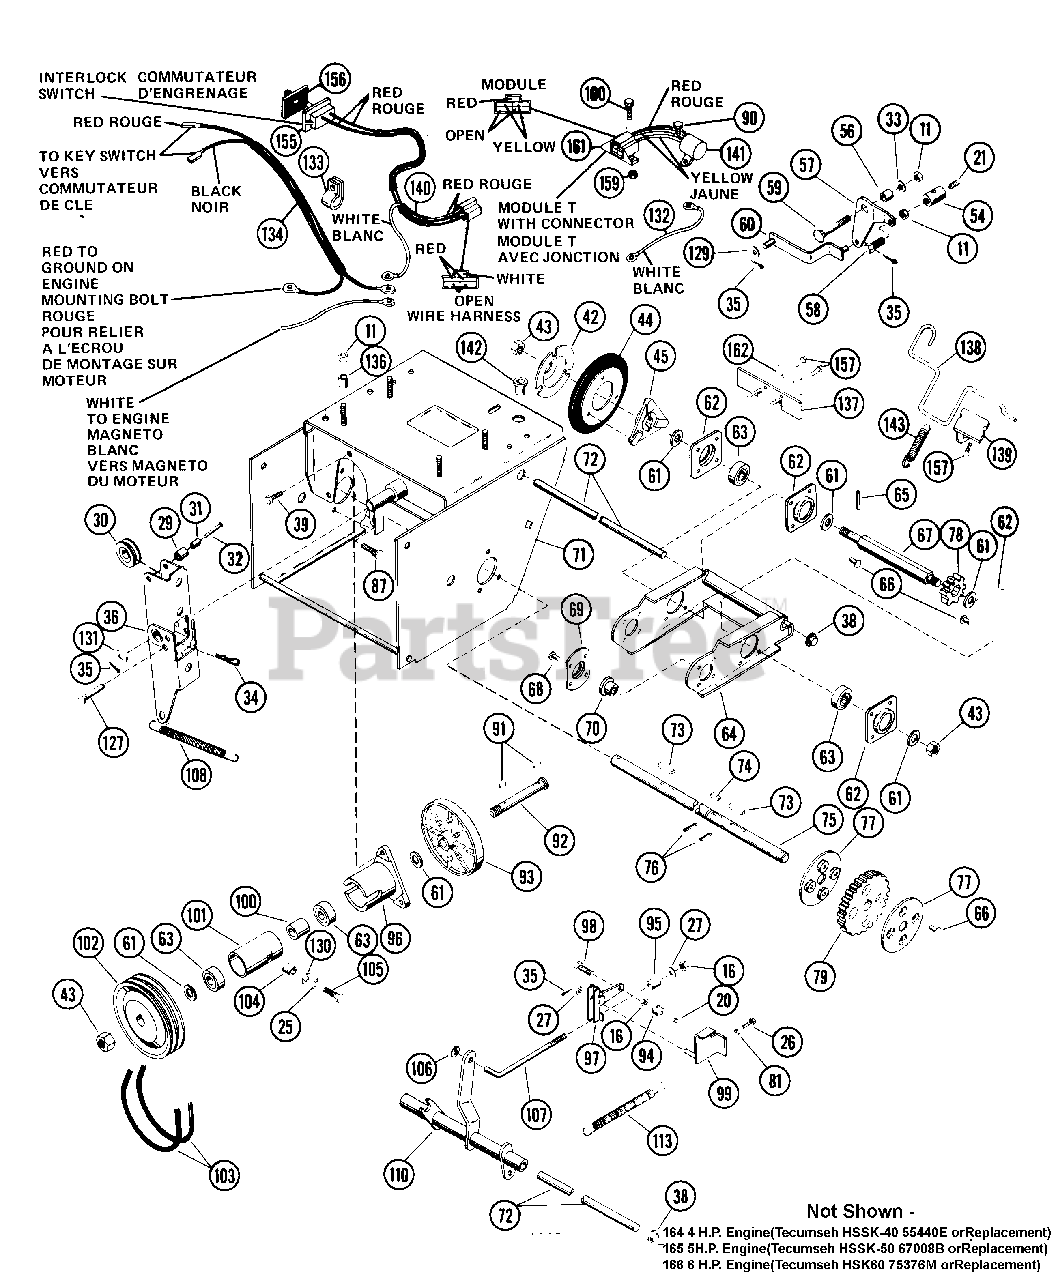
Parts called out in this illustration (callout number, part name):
11	NUT-LK .312-18 GR A PL
16	NUT-LK-CTR .250-20 PL
20	SCR-SET .25-20X.25 SKHCUPNY OH
21	SCR-SET .32-18X.38 SKHCUPNL OH
25	WSHR-LK .312X.097 PL HVY
26	BLT-HEX .25-20X.50 PL GR2
27	WSHR-FL-STL .250X.562X.049 PL
29	BSHG-SLV .500X.625X.937
31	IDLER SHAFT
32	RVT-TBLR .187X1.218 OH ST PL
33	WSHR-FL-STL .38X.875X.083 PL
34	PIN-HAIR INT .08X.18X1.18
35	PIN-COTR .09X.75 PL
36	IDLER ARM ASSEMBLY
38	CAP, .50 ROD YWZC
39	BLT-SERHFWH .31-18X.50 PL
42	RETAINER
43	NUT-LK-CTR .50-20 PL
44	FRICTION DISC
45	FRICTION DISC HUB
54	ROD ADAPTER
56	BSHG-SLV .334 X .502 X 1.437
57	SHIFT LEVER
58	BLT-HEX .31-18X.75 PL GR2
59	BLT-RDHDSQNK .31-18X2.0 SHT PL
60	SHIFT LINK
61	WSHR-FL-STL .505X1.000X.062
62	BEARING FLANGE
63	BRG-BALL .500X1.38X.437
64	CARRIER
65	PIN-ROLL .188X1.00
66	RVT-POP .187X.402 DOME ST
67	HEX SHAFT
68	RVT-POP.125 X .294 DOME
69	BEARING RETAINER
70	BSHG-FLG .750X1.000X.625X1.250
71	TRACTOR FRAME
73	KEY-FTHR .188X1.25X.187 SAE
74	KEY-WDRF .25X.750X.313 SAE91
75	AXLE SHAFT
76	PIN-ROLL .125X1.00
77	RETAINER PLATE
79	SPUR GEAR, FELLOWS 35T .750 ID
81	WSHR-LK .250X.077 HVY PL
90	BLT-SERHFWH .25-20X.50 PL
91	KEY-WDRF .125X.500X.203 SAE 3
92	SPINDLE
93	DRIVE DISK
94	ROD ADAPTER
96	DRIVE SPINDLE HOUSING
97	DEADMAN LEVER
98	BLT-HEX .25-20X.75 PL GR5
99	DEADMAN BRACKET
100	BEARING SPACER .75 X .5 X.88
101	SPINDLE HOUSING
102	DRIVE SHEAVE
103	V-BELT, SPECIAL-RAW EDGE (SET)
105	BLT-HEX .31-18X1.00 PL GR 2
106	RATCHET PLATE
107	ADJUSTMENT LINK
108	SG-TENS .063X.44X2.81 WLD 18
110	CLUTCH FORK
113	SG-TENS .063X.44X2.81 WLD 18
127	CLEVIS PIN
129	WSHR-FL-STL .250X.562X.125 PL
130	WSHR-FL-STL.344X.688X.065PL
131	WSHR-FL-STL.406X.812X.065PL
132	WIRE GROUND
134	SHORTING WIRE
136	ENG BOLT SPCR
137	BRACKET SWITCH
138	ACTUATOR SWITCH
139	RETAINER ROD
140	WIRING HARNESS
141	MODULE T SERVICE ASSEMBLY
142	SNAP BUSHING-.437
143	SG-TENS .026X.38X3.75 WLD 1.58
156	SWITCH BOOT
157	SCR-TAP 10-24X.375 HWH PL TR
159	NUT-LK TOP 10-24 PL
160	BLT-HEX 10-24X.38 PL GR2
161	CONNECTOR
162	STRAP - SWITCH BRACKET
163	BLT-SERHFWH .25-20X.50 PL
164	4 H.P. Engine(Tecumseh HSSK-40 55440E orReplacement)
165	5 H.P. Engine(Tecumseh HSSK-50 67008B orReplacement)
166	6 H.P. Engine(Tecumseh HSK60 75376M orReplacement)
